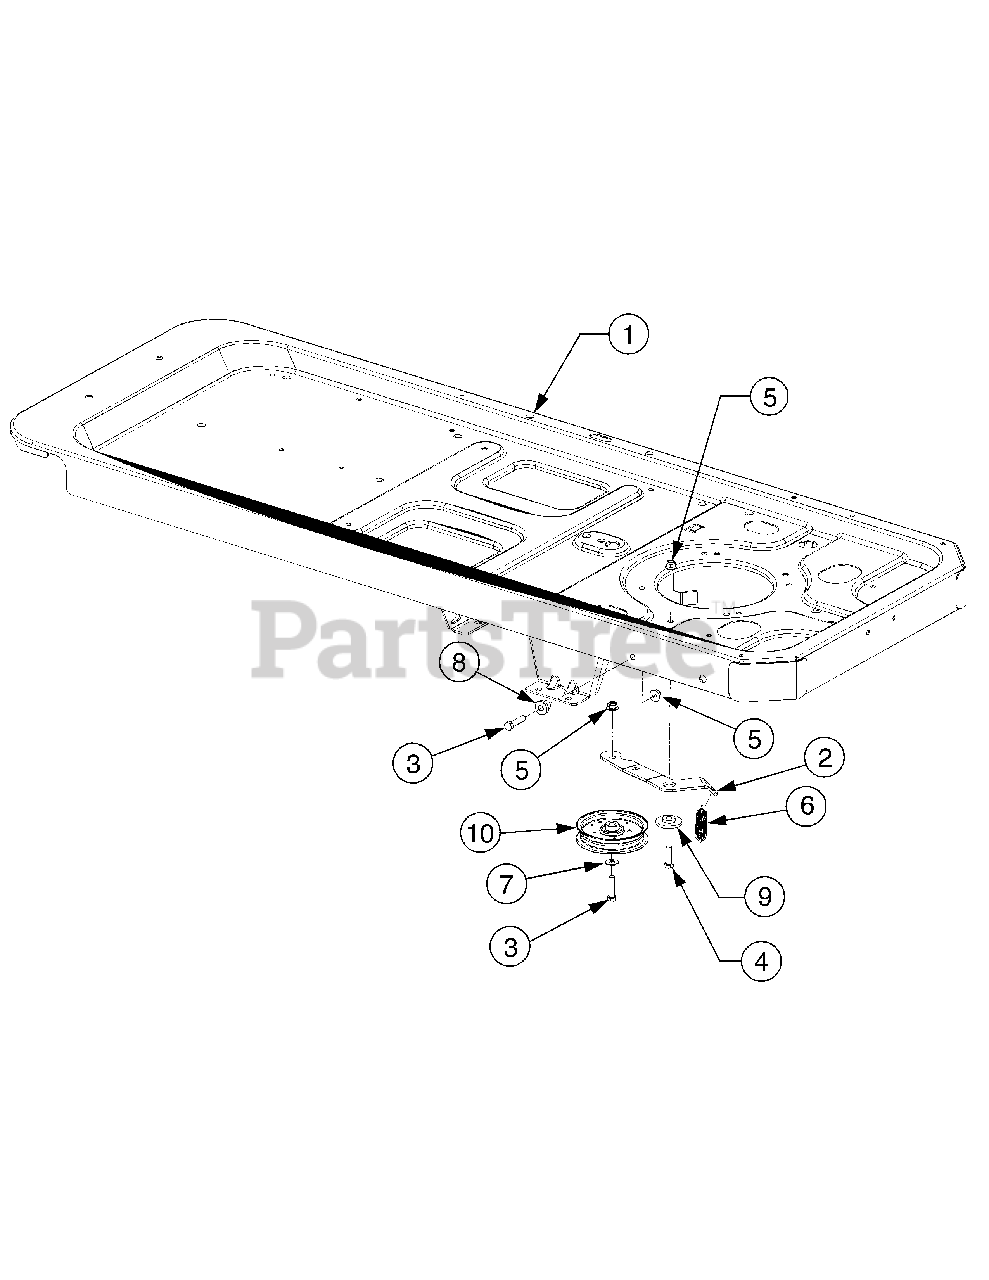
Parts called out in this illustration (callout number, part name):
1	Graphic, Release Lever
3	Screw, Hex Cap, 3/8-16 x 1.5 GR5
4	Screw, Hex Cap, 3/8-16 x 1.25 GR5
5	Nut, Hx Insert Flnge Lck, 3/-16 GrF
6	Spring, Extension, .75 x 5.06
7	Washer, Flat, .408 x .875 x .059
8	Spacer, Shoulder, .39 x 1.0 x .7
9	Spacer, Shoulder, .884 x .19
10	Pulley, Idler, 4.25 Dia.
